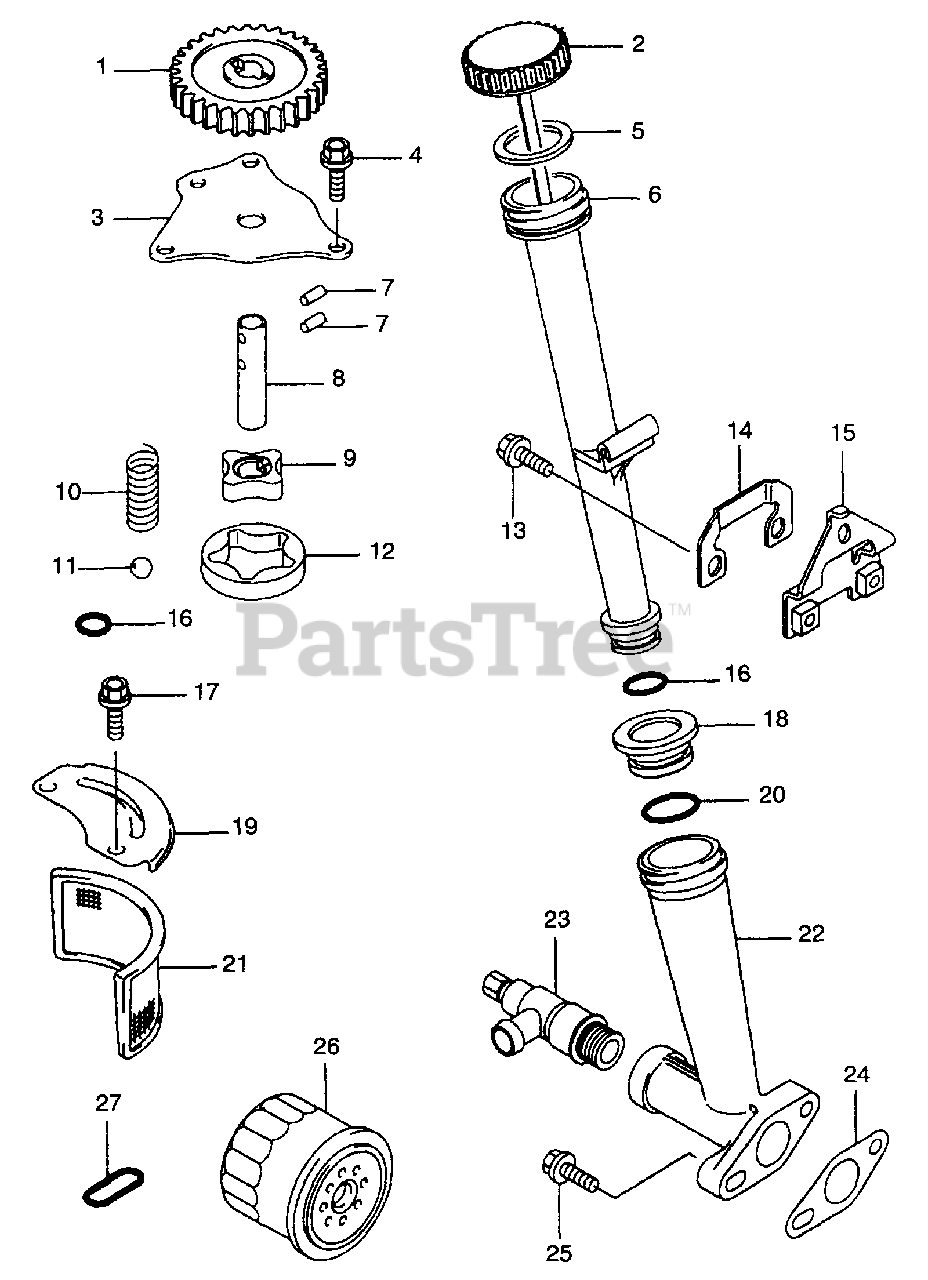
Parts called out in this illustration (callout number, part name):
3	Oil Pump Cover
4	Flanged Bolt
5	Oil Gauge Gasket
8	Oil Pump Shaft
9	Rotor-Pump In
10	Spring
12	Rotor-Pump Out
13	Flanged Bolt
17	Flanged Bolt
23	Fitting
24	Filler Gasket
25	Flanged Bolt
26	Oil Filter
